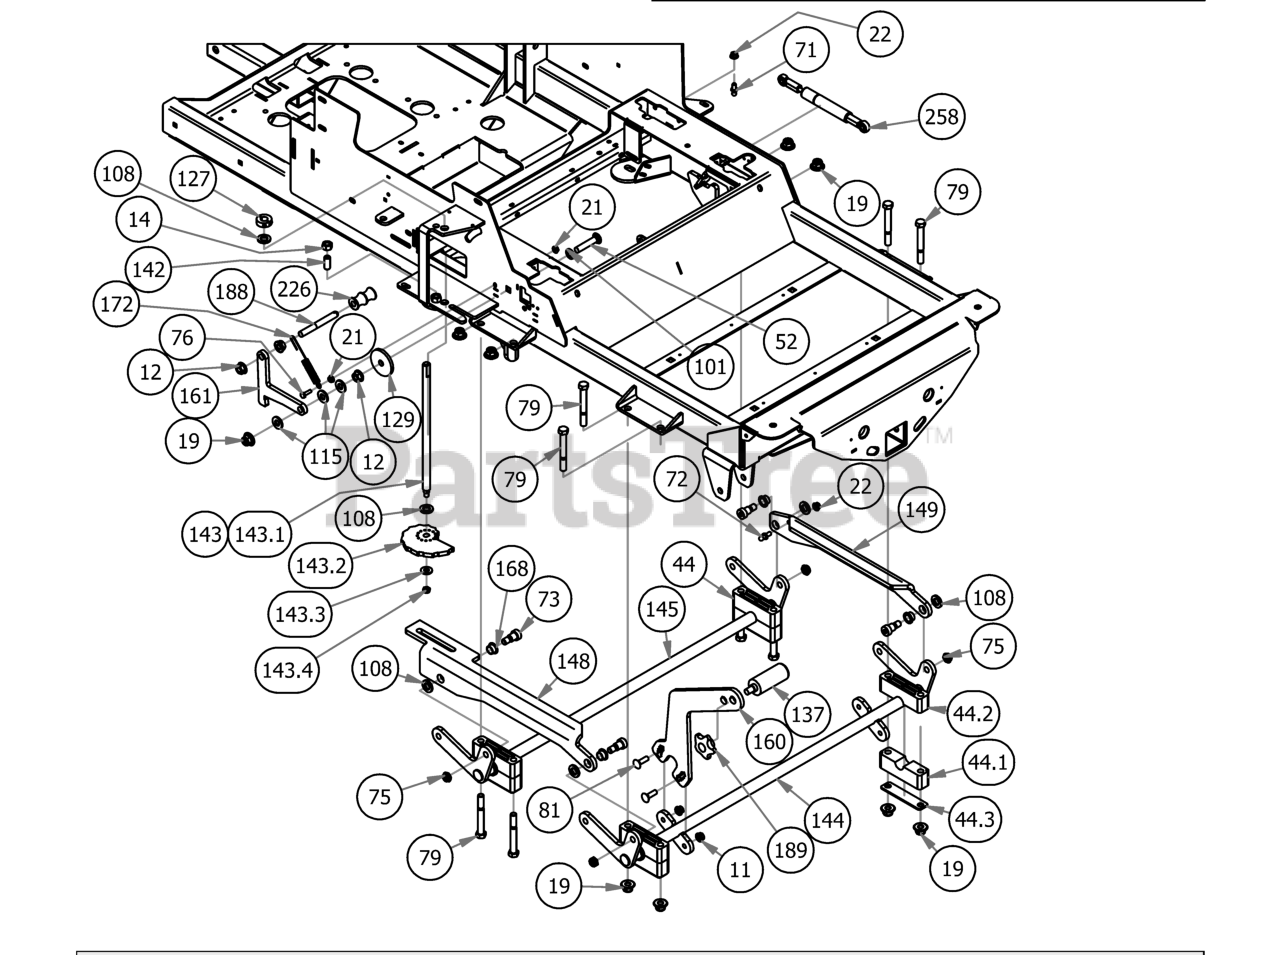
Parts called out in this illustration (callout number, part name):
11	3/8-16 NYLON INSERT FLANGE LOCKNUT (GR.F) ZINC
12	1/2" Flange Nut
14	1/2" Hex Nut
19	1/2-13 NYLON INSERT FLANGE LOCKNUT ZINC
21	1/4-20 Hex Flange Nuts Zinc w/Serrations
22	5/16" Flange Nut
44	Pillow Block Assembly
44.1	Two Piece Pillow Block (Male)
44.2	Two Piece Pillow Block (Female)
44.3	Two Piece Pillow Block Strap
52	1/2 x 2-1/2 Carriage Bolt
71	10mm Damper Ball Stud-Steering
72	10mm Damper Ball Stud-XP Linkage
73	5/8'' x 5/8'' Shoulder Bolt
75	1/2" Nylcock Nut (1/2 Jam)
76	1/4-20 x 1-1/4 GR 5 Hex Bolt
79	1/2" x 4" Bolt (Grade 8)
81	3/8" x 1 1/4" Carriage Bolt
101	.517 Square Hole Round Washer
108	.635 ID X 1.120 OD X .140 THICK FLAT WASHER NYLON
115	.505 Nylon Spacer
127	5/8" Split Collar
129	MZ Deck Idler Spacer
137	Knurled Pedal
142	Dial Rod Plunger
143	2019 Outlaw Gen2 Deck Height Dial Rod Assy
143.1	2019 Outlaw Gen2 Dial Rod
143.2	2019 Deck Height Cam
143.3	3/8" Flat Washer
143.4	3/8-24 Nylon Insert jam locknut
144	2019 Outlaw Actuator - Front
145	2019 Outlaw Actuator - Rear
148	2019 Actuator Linkage - Right
149	2019 Actuator Linkage - Left
160	Foot Lift Upright Lever
161	2019 Outlaw Deck Travel Lock
168	Bronze Bushing - SF - 2024-8
172	Brake Spring
188	Seat Bracket Pin
189	Foot Pedal Knob 1/2-13
226	Travel Lock Rubber Grip
231	2019 Horizontal Diesel Frame
258	250lb Gas Spring - 61" Deck
